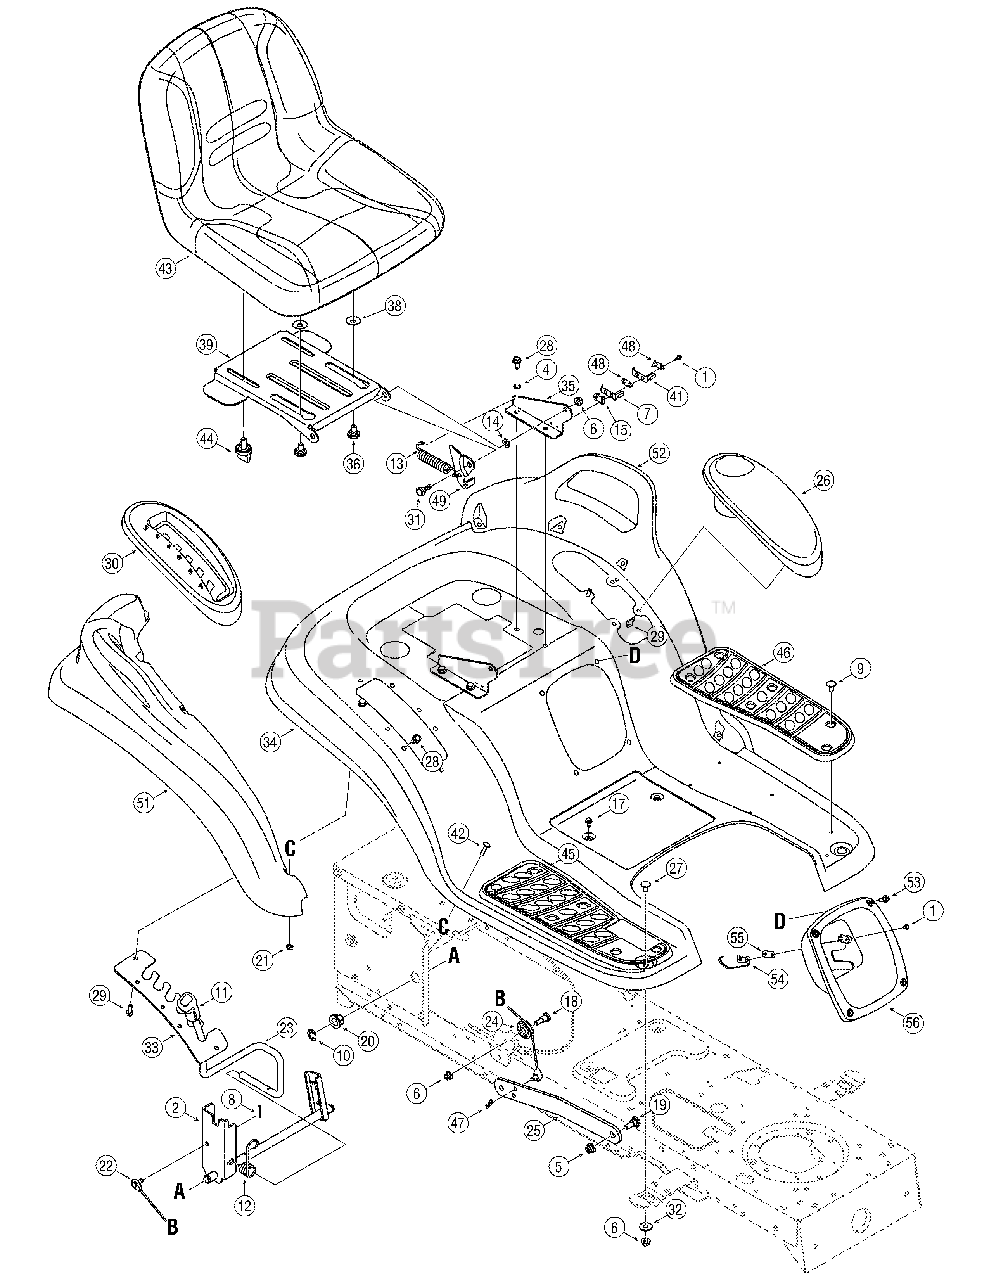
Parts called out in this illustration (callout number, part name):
1	Screw, #8-18 x.500
4	Lock Washer, 5/16
5	Flange Lock Nut, 3/8-16
6	Flange Lock Nut, 5/16-18
7	Inner Seat Spring Switch
8	Hairpin Clip
9	Foot Pad Clips
11	Handle Grip
12	Torsion Spring
13	Extension Spring,.84 x 4.6
14	Flat Washer
15	Insulator Boss Plate
16	Flat Washer,.31 x 1.062 x.134
17	Screw, 1/4-20 x.500
18	Hex Cap Screw, 5/16-18 x.62
19	Shoulder Screw, 3/8-16
20	Hex Flange Bearing
21	Sems Nut 1/4-20
22	Lift Cable, 16.16
23	Lift Handle
24	Roller Pulley
26	Cover w/ Cup Holder
27	Carriage Bolt, 5/16-18 x.750
28	Self-tapping Screw, 5/16-18 x.625
29	Self-tapping Screw, 1/4-15 x.75
30	Lift Lever Cover
31	Shoulder Screw,.437 x.286
32	Flat Washer,.349 x 1.0 x.063
36	Shoulder Screw, 3/8-16
37	Flange Lock Nut, 1/4-20
38	Flat Washer,.406 x .875 x .059
40	Compression Spring,.41 x 1.5
41	Outer Seat Spring Switch
42	Carriage Screw 1/4-20 x 1.00
43	High Back Seat, Black
44	Adjustment Knob, 3/8-16 x .875
45	RH Foot Pad
46	LH Foot Pad
47	Cotter Pin
48	Insulator Plate
49	Seat Lift Bracket
50	Speed Clip
51	RH Fender Flare
52	LH Fender Flare
53	Screw, 1/4-20 x.750
54	Spring Switch
55	Insulator Plate
56	Shift Cover
